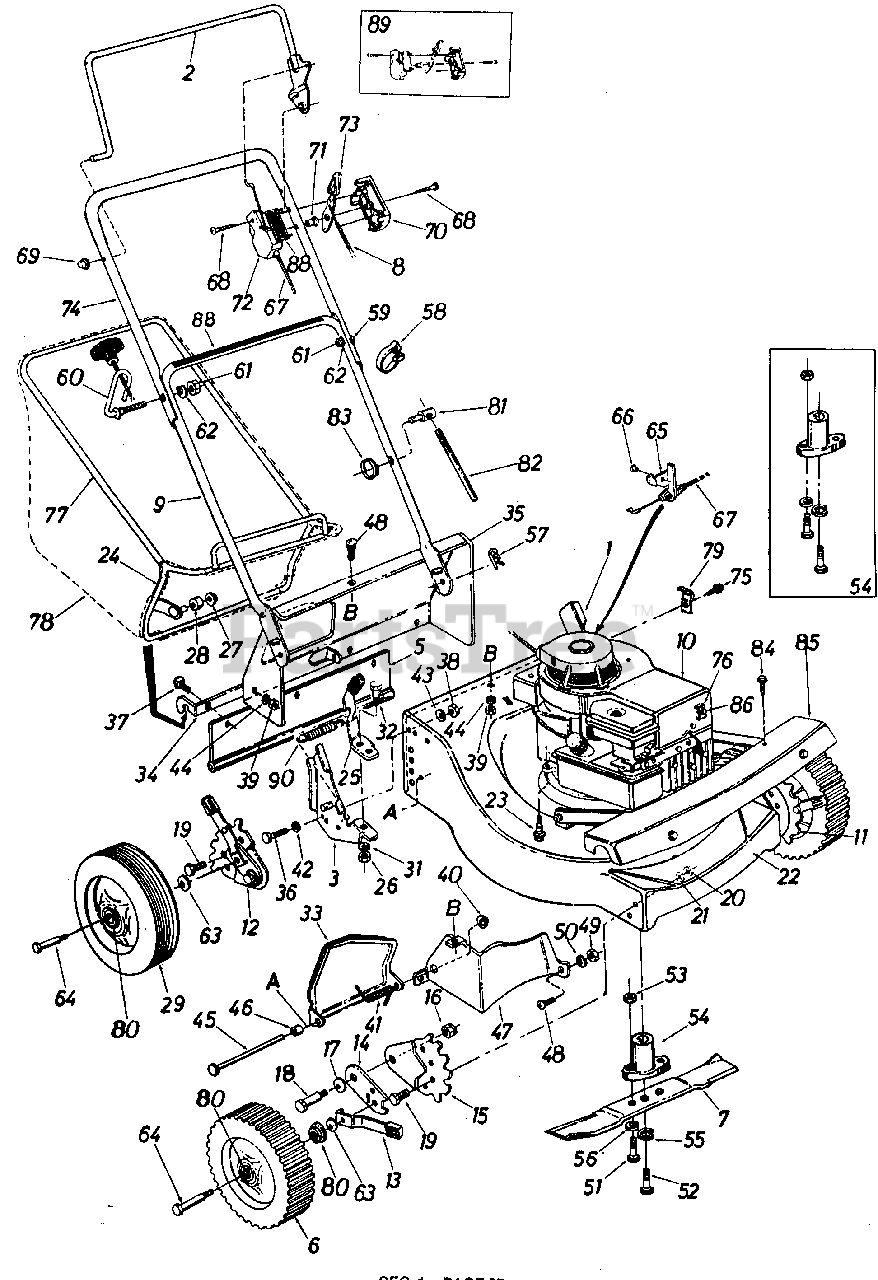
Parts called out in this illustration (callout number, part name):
2	Control Handle Ass'y.-L.H.
3	Handle Brkt. Ass'y.-R.H.
5	Rear Flap Ass'y.
6	Wheel Ass'y. Comp. 8 x 1.75
7	20" Blade
8	Throttle Wire-58.0"
9	Lower Handle
10	Engine
11	L.H. Height Adj. Ass'y.
12	R.H. Height Adj. Ass'y.
13	Spring Lever Ass'y. w/Knob
14	Wheel Pivot Bar
15	Index Plate
16	Hex Cent. L-Nut 3/8-16 Thd.
17	Bell-Wash. .515 I.D. x 1.14" O.D. x .040
18	Shld. Bolt .500" Dia. x .245
19	Hex Bolt 3/8-16 x .75" Lg.
20	Hex Nut 3/8-16 Thd.
21	L-Wash. 3/8" I.D.
22	20" Deck Ass'y.
23	Self-Tap Screw 3/8-16 x 1.0"
26	Hex Nut 5/16-18 Thd.*
27	Push Nut 3/8" Rod
28	Plastic Roller
29	Wheel Ass'y. Comp. 8 x 1.75
31	L-Wash. 5/16" I.D.
32	Shld. Bolt .437" Dia. x .162
33	Chute Door
34	Grass Catcher Hitch Brkt.
35	Rear Discharge Deck Section
36	Hex Bolt 1/4-28 x .75" Lg.
37	Carr. Bolt 1/4-20 x .75" Lg.
38	Hex Nut 1/4-28 Thd.
39	Sems Nut 1/4-20 Thd.
40	Push Nut 1/4" Rod
41	Torsion Spring
42	L-Wash. 1/4n I.D.
43	Bell-Wash. 1/4" I.D. x .88n O.D.
44	Fl-Wash. .285" I.D. x 1.25" O.D.
45	Hinge Pin .250" Dia. x 7 25"
46	Spacer .262" I.D. x .31" O.D. x .58
47	Rear Baffle
48	Carriage Bolt 1/4-20 x .50"
49	Hex Nut 1/4-20 Thd.
50	L-Wash. 1/4" I.D.
51	Hex Bolt 5/16-24 x 1.00" Lg. (Grade 5)
52	Hex Bolt 3/8-24 x 2.25" Lg. (Grade 5)
53	Hex Nut 5/16-24 Thd.
54	Blade Adapter Kit
55	L-Wash. 3/8" I.D.-H.D.
56	L-Wash. 5/16" I.D.
57	Intern. Cot. Pin 5/16" Dia.
58	Cable Tie
59	Curved Carriage Bolt 5/16-18 x 1.38" Lg.
60	Rope Guide Bolt
61	Hex Nut 5/16-18 Thd.
62	L-Wash. 5/16" I.D.
63	Bell-Wash. .400" I.D. x .88" O.D. x .060
64	Axle Bolt
65	Cable Bracket
66	Pop Rivet .156" Dia. x .379
67	Brake Control Cable-43.0"
68	Truss Mach. Hd. "B" Tap Scr. #12 x 1.50" Lg.
69	Cap Speed Nut 5/16" Rod
70	Control Panel Half
71	Control Disc Pin
72	Control Panel Half
73	Throttle Control Lever
74	Upper Handle
75	Hex AB-Tap Scr. #10 x .38ø
76	Casing Clamp
77	Grass Catcher Upper Frame
78	Grass Bag
79	Casing Clamp
80	Fortiflex Bearing
81	Ferrule
82	Clutch Rod
83	Ferrule Locking Ring
84	Hex Wash. Hd. Self-Tap Scr. 1/4 -20 x .50" Lg .
85	Drive Cover
86	Hex Wash. Hd. AB-Tap Scr. #8 x .38" Lg.
88	Instruction Labels
89	Kit-Control Housing Complete
90	Extension Spring
